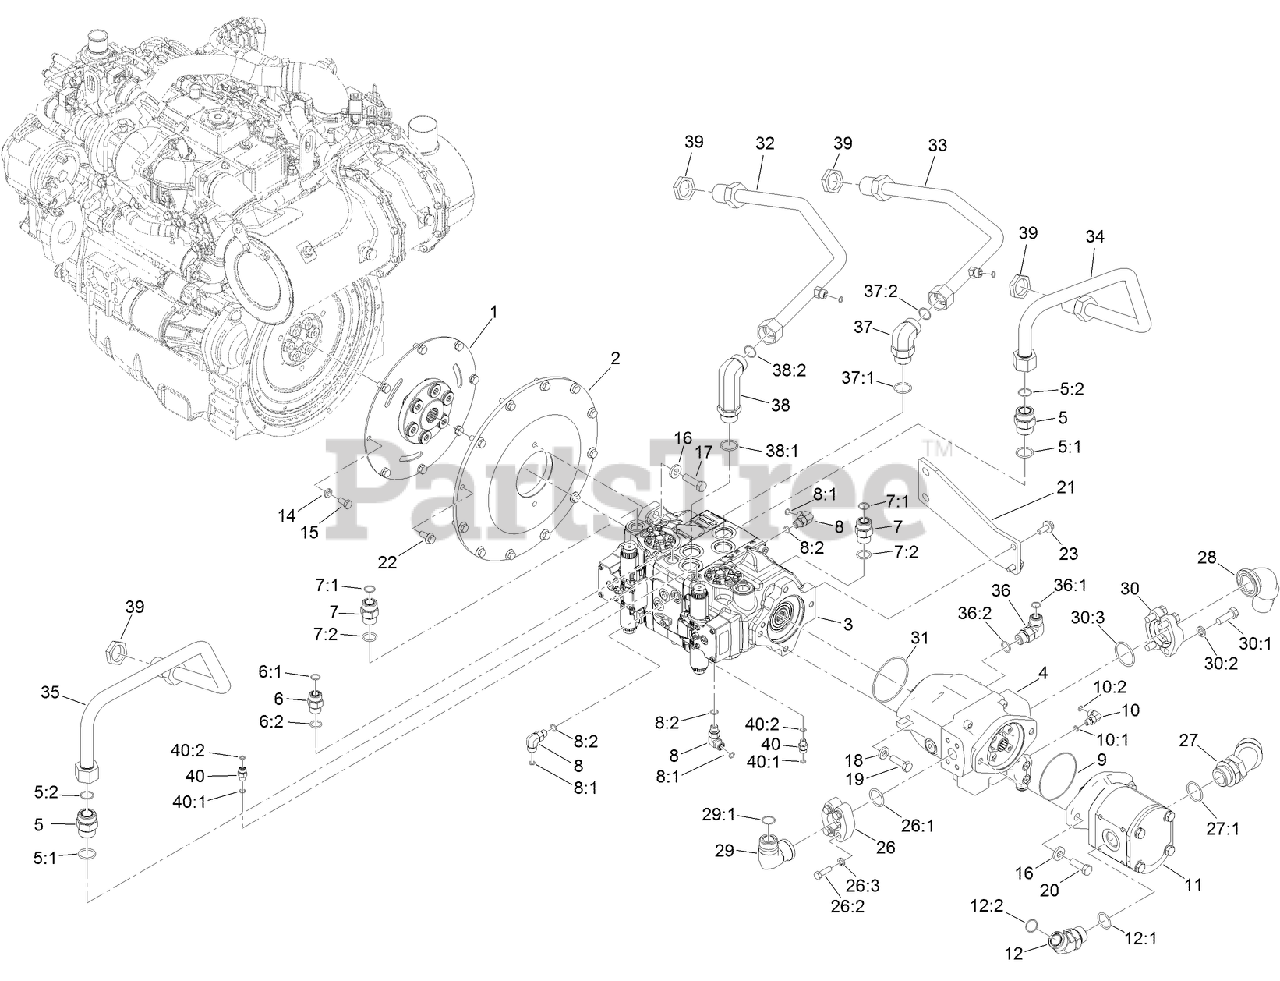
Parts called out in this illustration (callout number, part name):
1	COUPLER-FLYWHEEL
2	COVER-FLYWHEEL
3	PUMP-HYDROSTAT
4	PUMP-PISTON, LOAD SENSE
5	FITTING-STRAIGHT
5:1	O-RING
5:2	O-RING
6	FITTING-STRAIGHT
6:1	O-RING
6:2	O-RING
7	FITTING-HYD, STRAIGHT
7:1	O-RING
7:2	O-RING
8	FITTING-ELBOW, 90 DEG
8:1	O-RING
8:2	O-RING
9	O-RING
10	FITTING-ELBOW, 90 DEG
10:1	O-RING
10:2	O-RING
11	GEAR PUMP ASM
12	FITTING-HYD, 45 DEG
12:1	O-RING
12:2	O-RING
14	WASHER-PLAIN
15	SCREW-HH
16	WASHER-HARDENED
17	SCREW-HH
18	WASHER-SPACER, HARDENED
19	BOLT-HH
20	SCREW-HH
21	BRACKET-SUPPORT, PUMP
22	SCREW-HHF
23	SCREW-HHF
26	FLANGE KIT
26:1	O-RING
26:2	SCREW-HH
26:3	WASHER-LOCK
27	FITTING-HYD-45
27:1	O-RING
28	FITTING-HYD-90
29	FITTING-HYD-90
29:1	O-RING
30	FLANGE KIT
30:1	SCREW-HH
30:2	SCREW-HH
30:3	O-RING
31	O-RING
32	TUBE ASM-HYD
33	TUBE ASM-HYD
34	TUBE ASM
35	TUBE ASM
36	FITTING-ELBOW, 90 DEG
36:1	O-RING
36:2	O-RING
37	FITTING-ELBOW, 90 DEG
37:1	O-RING
37:2	O-RING
38	FITTING-ELBOW, 90 LONG
38:1	O-RING
38:2	O-RING
39	NUT-BULKHEAD
40	FITTING-STRAIGHT
40:1	O-RING
40:2	O-RING
